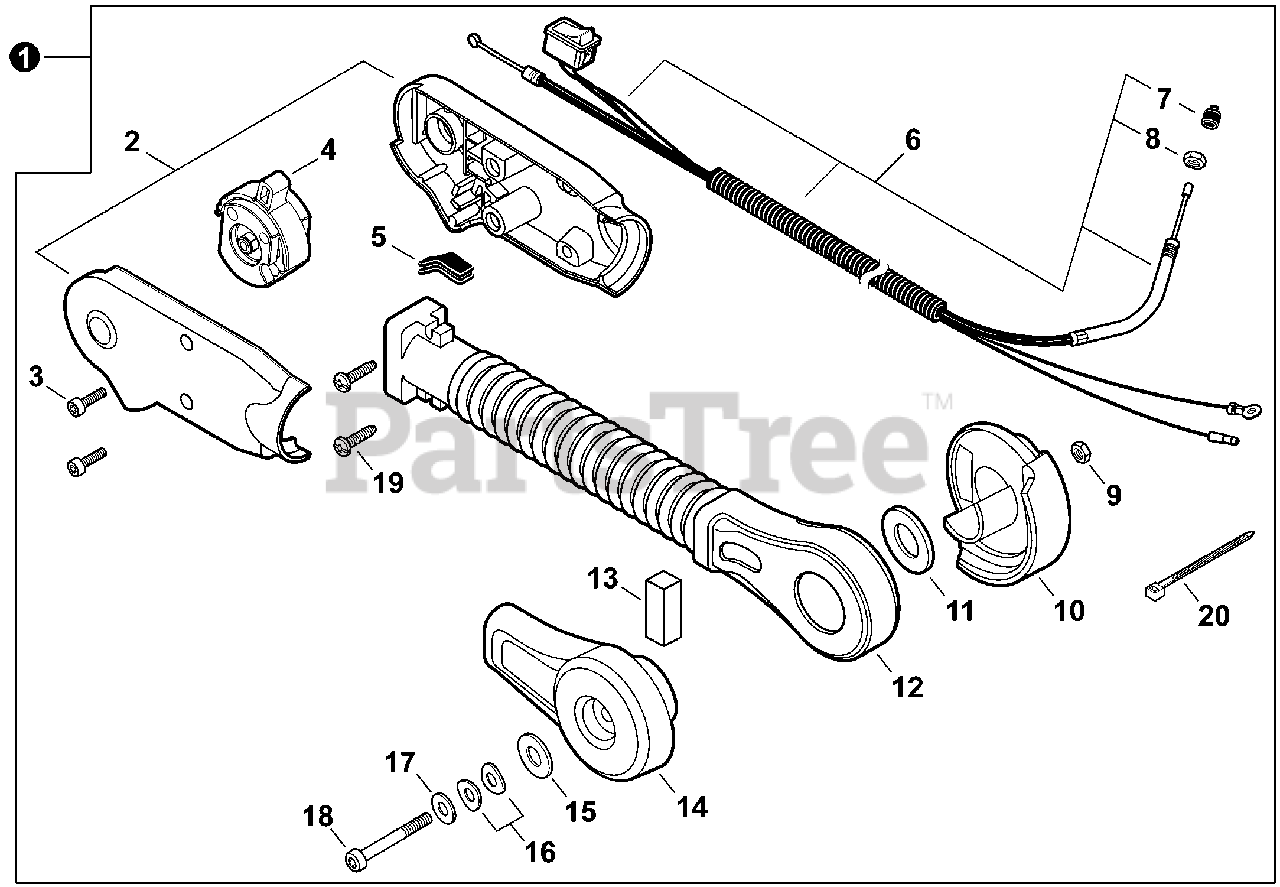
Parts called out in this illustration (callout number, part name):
1	THROTTLE CONTROL KIT - HIP MOUNT
2	GRIP SET, THROTTLE
3	BOLT, TORX 5×16
4	CONTROL, THROTTLE
5	GROMMET
6	CABLE ASSY, CONTROL
7	CAP, DUST
8	NUT, HEX M6
9	NUT, LOCK M6
10	BRACKET, ARM - INNER
11	WASHER 45
12	ARM, THROTTLE CONTROL
13	SEAL, DUST - FOAM
14	BRACKET, ARM - OUTER
15	WASHER 6.6×20×1.6
16	WASHER, FRICTION 6.6×14.3
17	WASHER 6.5×15.5×0.6
18	BOLT, TORX 6×75
20	STRAP, TIE
